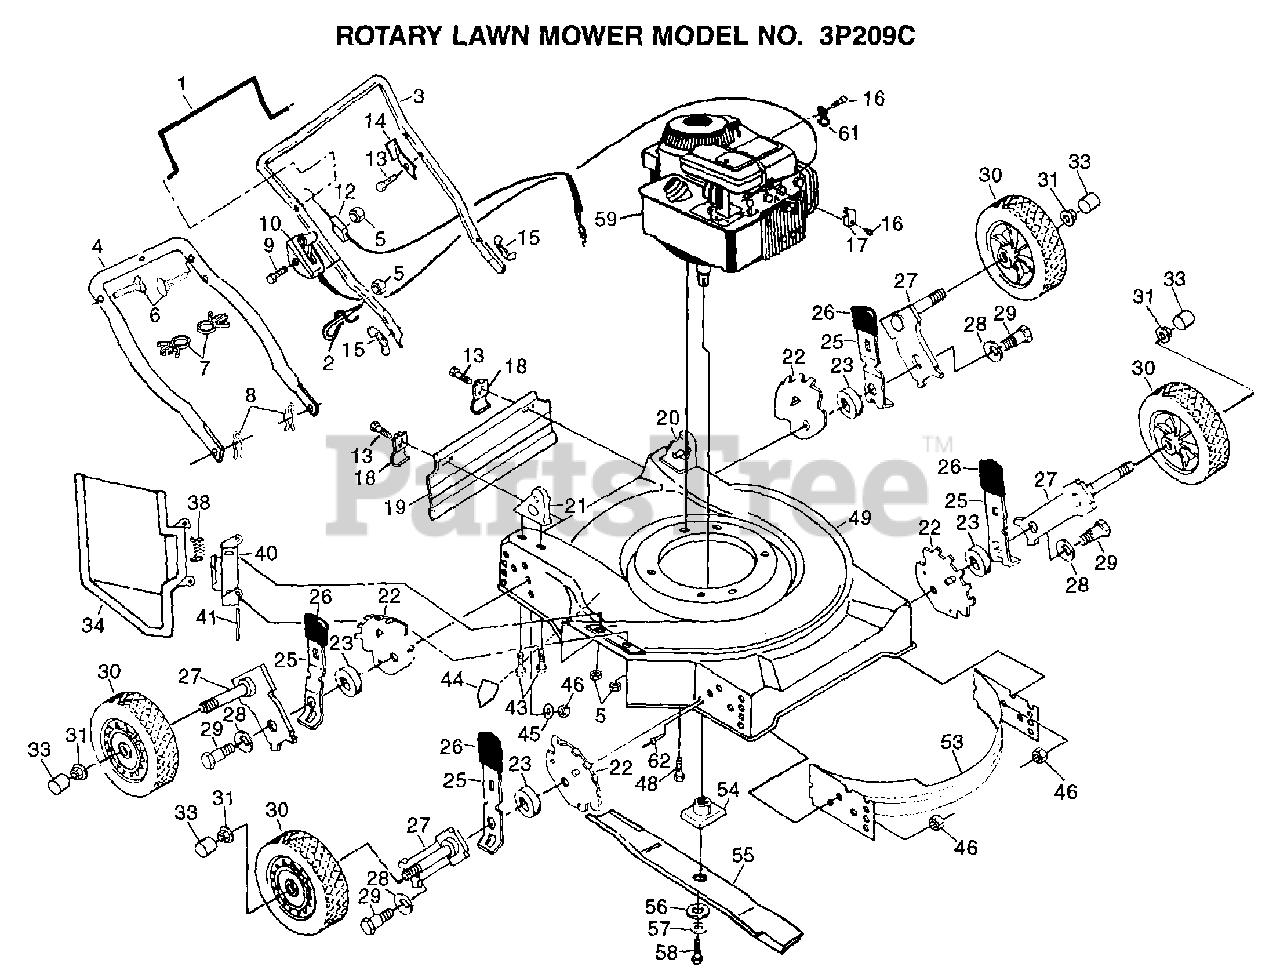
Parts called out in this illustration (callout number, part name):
1	CONTROL BAR PM
2	ROPE GUIDE
6	BOLT.HANDLE.LM
8	HAIRPIN COTTER
9	SCREW.HXHD.WASH.
10	CONTROL THROTTLE
12	"CABLE,ENG ZONE CO"
13	TAPPING SCREW
14	"BRKT,UPSTOP"
15	"NUT,WING PM"
16	SCREW PM
17	CABLE CLAMP
18	"BRKT,DEFL PM"
19	SKIRT.REAR.FGD.22
20	HDLE BRKT ASSY LH
21	HDLE BRKT ASSY.RH
22	BRACKET.ADJ.9POS.
23	SPACER.HEIGHT.ADJ
25	SPRING SELECTOR
26	KNOB PM
28	"WASHER, BELLEVIL."
29	BOLT SHLD 3/8-16
30	WHEEL.ASM
31	HEX FLANGE LOCKNT
33	HUB CAP-PLASTIC
34	GUARD.DISCH.22SD.
40	BRACKET.HINGE.W/F
41	ROD.HINGE.COMBI-C
43	SCREW 5/16-18X3/4
44	DECAL HYT
46	LOCKNUT PM
48	BOLT.ENG.3/8-16
53	BAFFLE.FRT/REAR
54	BLADE ADAPTOR
55	"BLADE.MULCH.22"""
56	"WASHER,HARDEN"
57	LOCKWASHER
58	SCREW
61	GUIDE CLIP PM
62	BLIND RIVET
